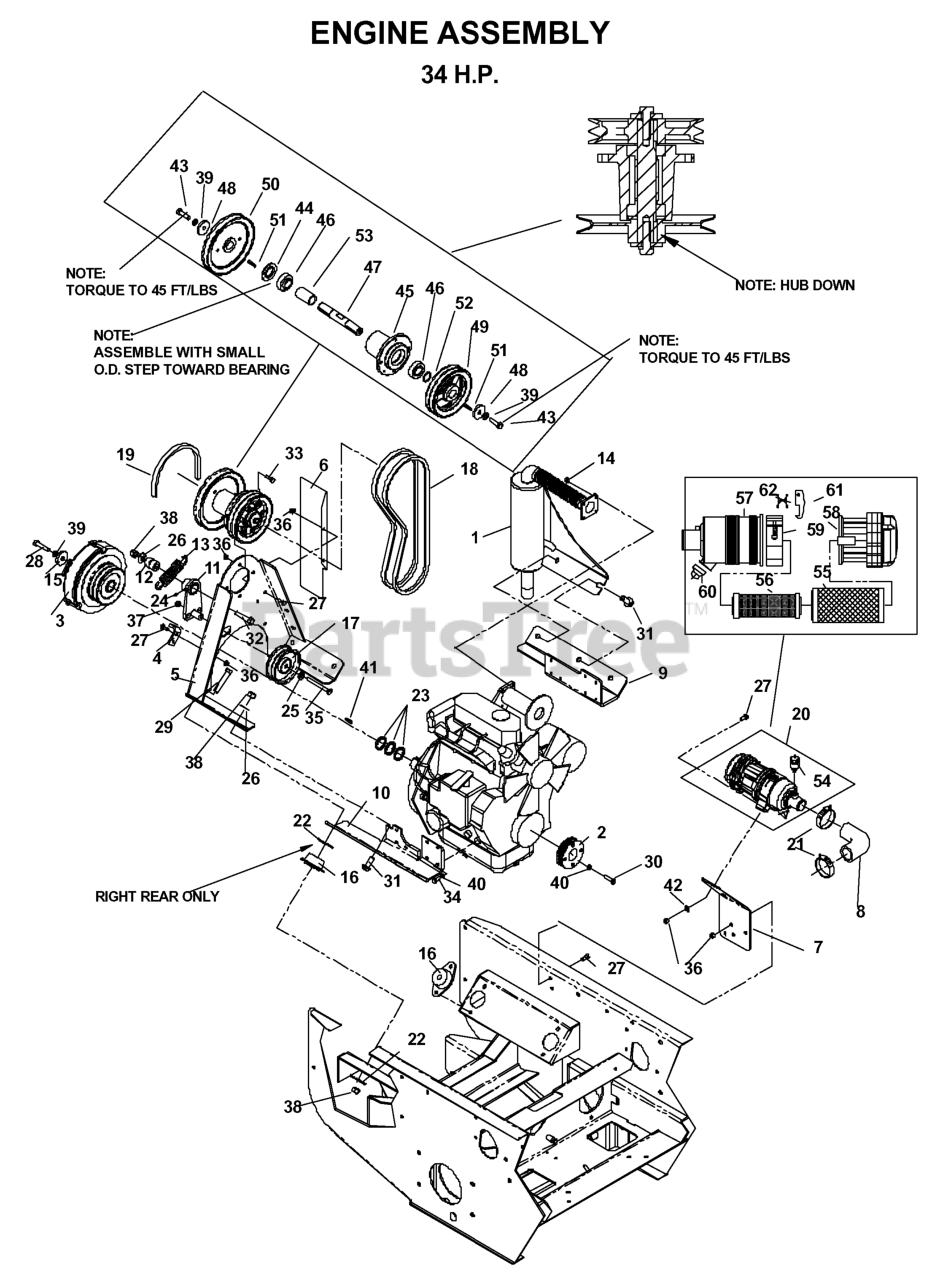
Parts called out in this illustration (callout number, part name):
1	MUFFLER
2	ENGINE SHEAVE
3	CLUTCH
4	RESTRAINT
5	JACKSHAFT MOUNT WELDMENT
6	HEAT SHIELD
7	MOUNTING BRACKET
8	AIR FILTER HOSE
9	ENGINE MOUNT-LT
10	ENGINE MOUNT-RT
11	ARM WELDMENT
14	NUT M8-1.25 STOVER
15	SPINDLE WASHER
17	IDLER, PRIMARY
18	ENGINE BELT, PRIMARY
19	ENGINE, BELT MULE
20	AIR FILTER ASSY
21	CLAMP, AIR HOSE
22	ISOLATOR WASHER
23	BUSH 1-1/8 X 10 GA ZD
24	ZERK
25	WASHER 3/8 SAE FLAT
26	WASHER 1/2 FLAT
27	HCS 5/16C X 3/4
28	BOLT 7/16F X 2 1/2
29	HCS 1/2C X 2 3/4
30	HTB M8-1.125 X 25MM
31	HCS 1/2C X 1 1/4 SERRATED HEAD
32	HEX SCREW 1/2-13 X 2.5" GR 5
33	HCS 5/16C X 1
35	HCS 3/8-16 X 3-1/2 GR5 ZD
36	NUT 5/16 NYLOC
37	NUT 3/8-16 NYLOC
38	NUT 1/2-13 HEX NYLOC ZD
39	WASHER 7/16 LOCK
40	WASHER.LOCK.HVY.HLCL.SPR.5/16
41	KEY 1/4" SQ X 1 7/8"
42	WASHER 5/16 FLAT
43	HCS 7/16F X 1 1/2
44	COMBO SPACER
45	HOUSING, DIE CAST
46	BEARING
48	SPINDLE WASHER
51	KEY 1/4 SQ X 1 1/8
52	BUSHING.MACHINE.18.GAUGE
55	AIR FILTER
56	SAFETY ELEMENT
57	BODY, STRAIGHT
58	PRECLEANER ASM
59	MOUNTING BRACKET
539106327	STUB SHAFT
539109177	MANIFOLD GASKET
